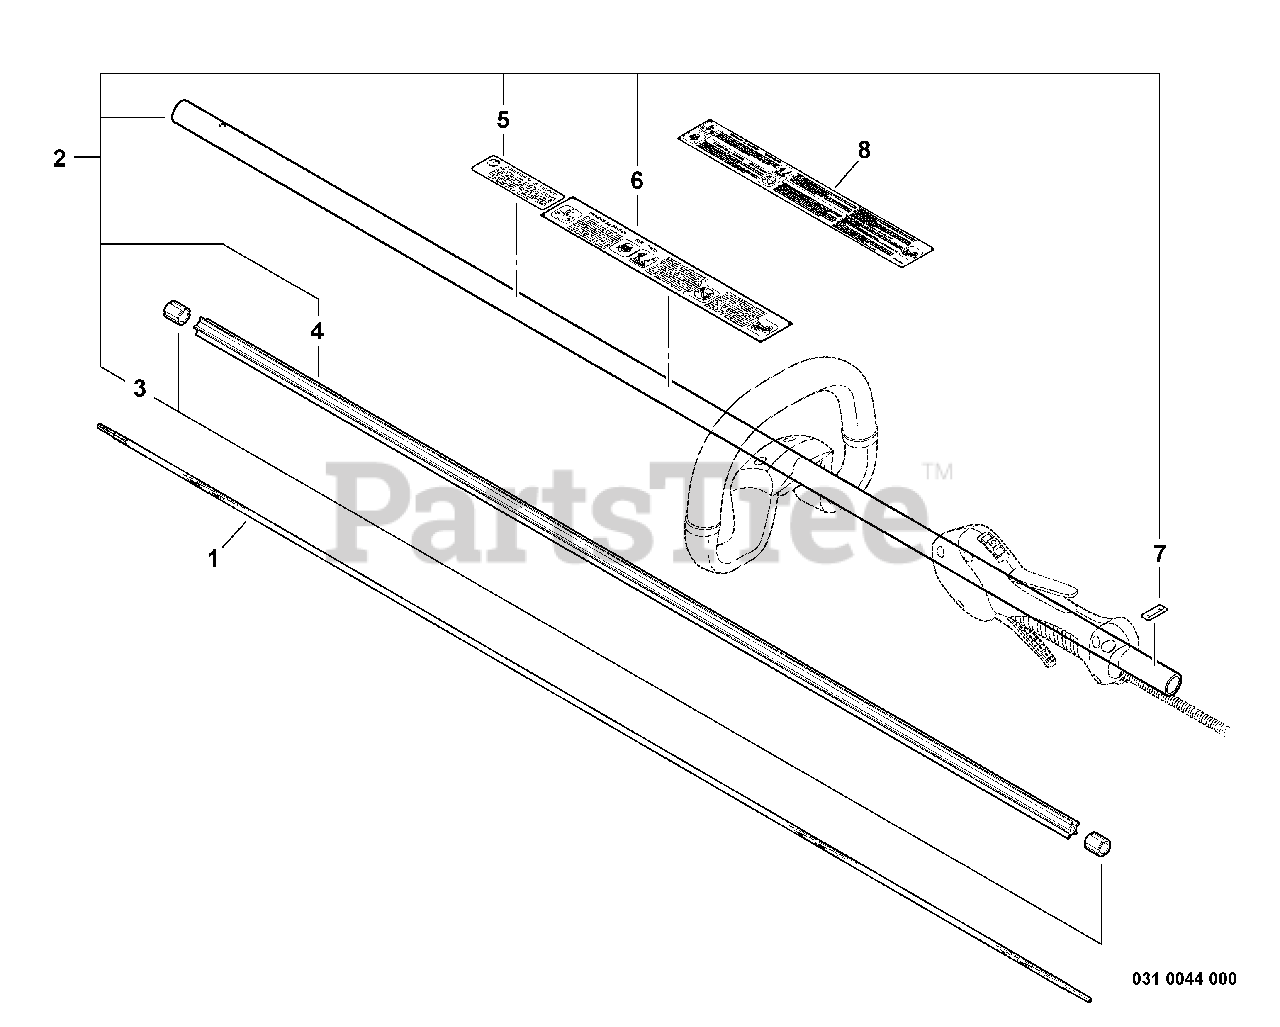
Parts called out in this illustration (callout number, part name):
1	DRIVESHAFT - FLEXIBLE
2	MAIN PIPE ASSY
4	LINER - FLEXIBLE
5	LABEL - CAUTION -- SPANISH
6	LABEL - CAUTION
7	LABEL - ALIGNMENT
8	LABEL - CAUTION
